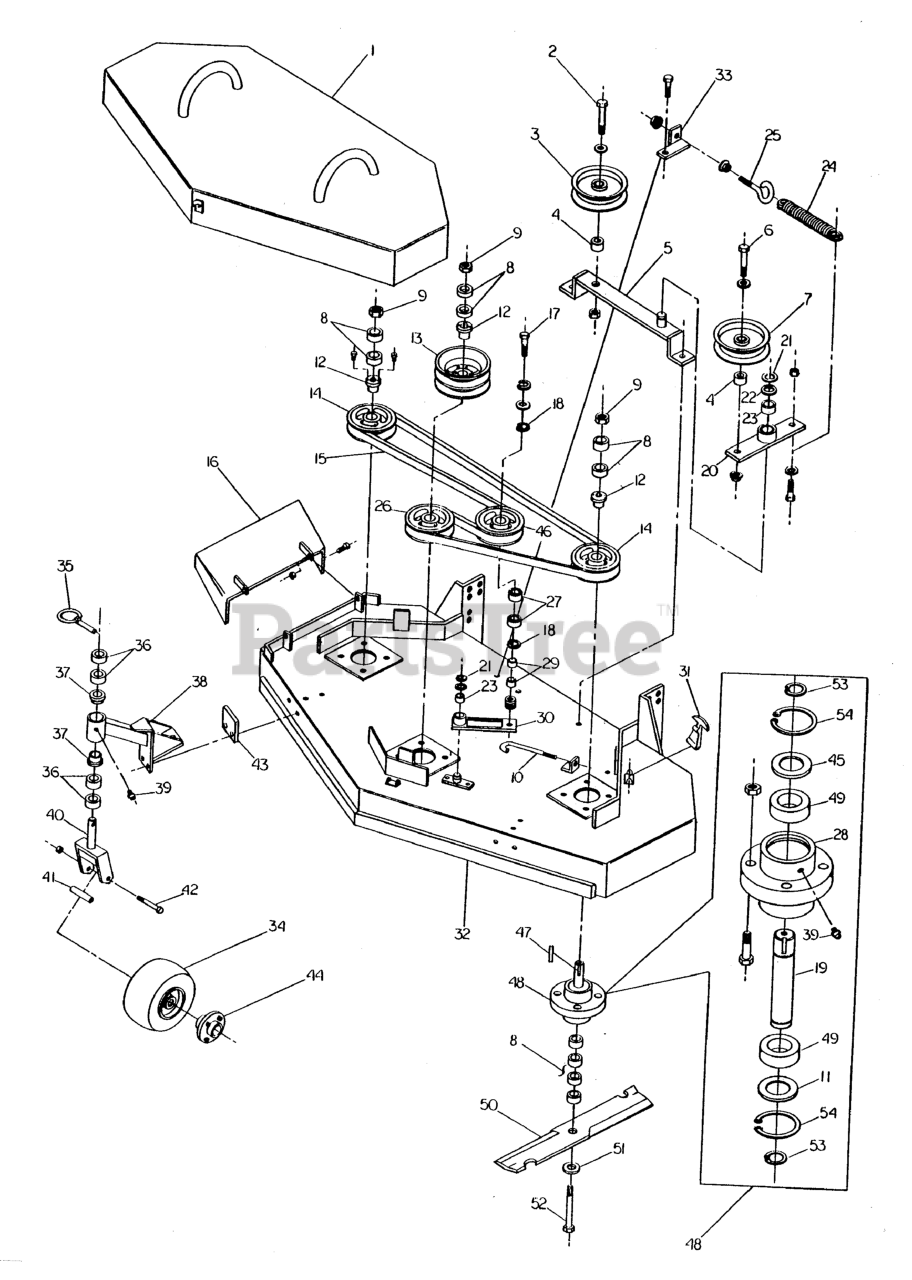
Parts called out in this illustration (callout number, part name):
1	48" DECK GUARD
2	1/2-13 x 3-1/2" Bolt
3	PULLEY, Backside Idler
4	SPACER, .50 x 1.00 X .69
5	Idler Mount
6	1/2-13 x 3" Bolt
7	PULLEY, V-Idler
8	SPACER, .63 x 1.06 x .23
9	NUT, 5/8-11 Hex
11	SPINDLE WASHER, Bottom
12	BUSHING, Tapered Hub
14	PULLEY, Spindle
15	BELT, Blade Spindle
16	CHUTE, DISCHARGE WELDMENT
17	1/2-20 x 2-1/4" Bolt
18	SNAP RING, Internal
19	SPINDLE SHAFT
20	IDLER ARM, Complete
21	C-CLIP
22	SHIM
23	BUSHING, Brass
24	SPRING, Extension
25	EYEBOLT
26	SPINDLE PULLEY
27	BEARING, BALL 11/16X1-9/16X15/32
28	SPINDLE HOUSING
29	INSERT, Bearing
30	IDLER ARM
31	RUBBER LATCH
32	48" MOWER HOUSING
33	Spring Anchor
34	WHEEL & TIRE ASSEMBLY, White, 9 x 3.5 x 4, Complete
34	TIRE, Front, 9 x 3.5 x 4
34	HUB & BEARING ASSEMBLY, Complete, White
35	PIN, Lynch
36	SPACER, 1.02 x 1.56 x .50
37	BUSHING, Flange
38	Caster Support
39	GREASE FITTING
40	YOKE, Caster
41	AXLE, Caster Wheel
42	1/2-13 x 5-1/2" Bolt
43	Caster Mount Spacer
44	Hub (Stamped M)
45	SPINDLE WASHER, Top
46	PULLEY, Idler
47	KEY, 1/4 SQ. X 2-1/2
48	SPINDLE ASSEMBLY, Complete
49	BEARING
50	MOWER BLADE, 16-1/4"
51	5/8 Washer
52	BOLT, 5/8-11 x 9-1/2
53	SNAP RING, External
54	SNAP RING, Internal
